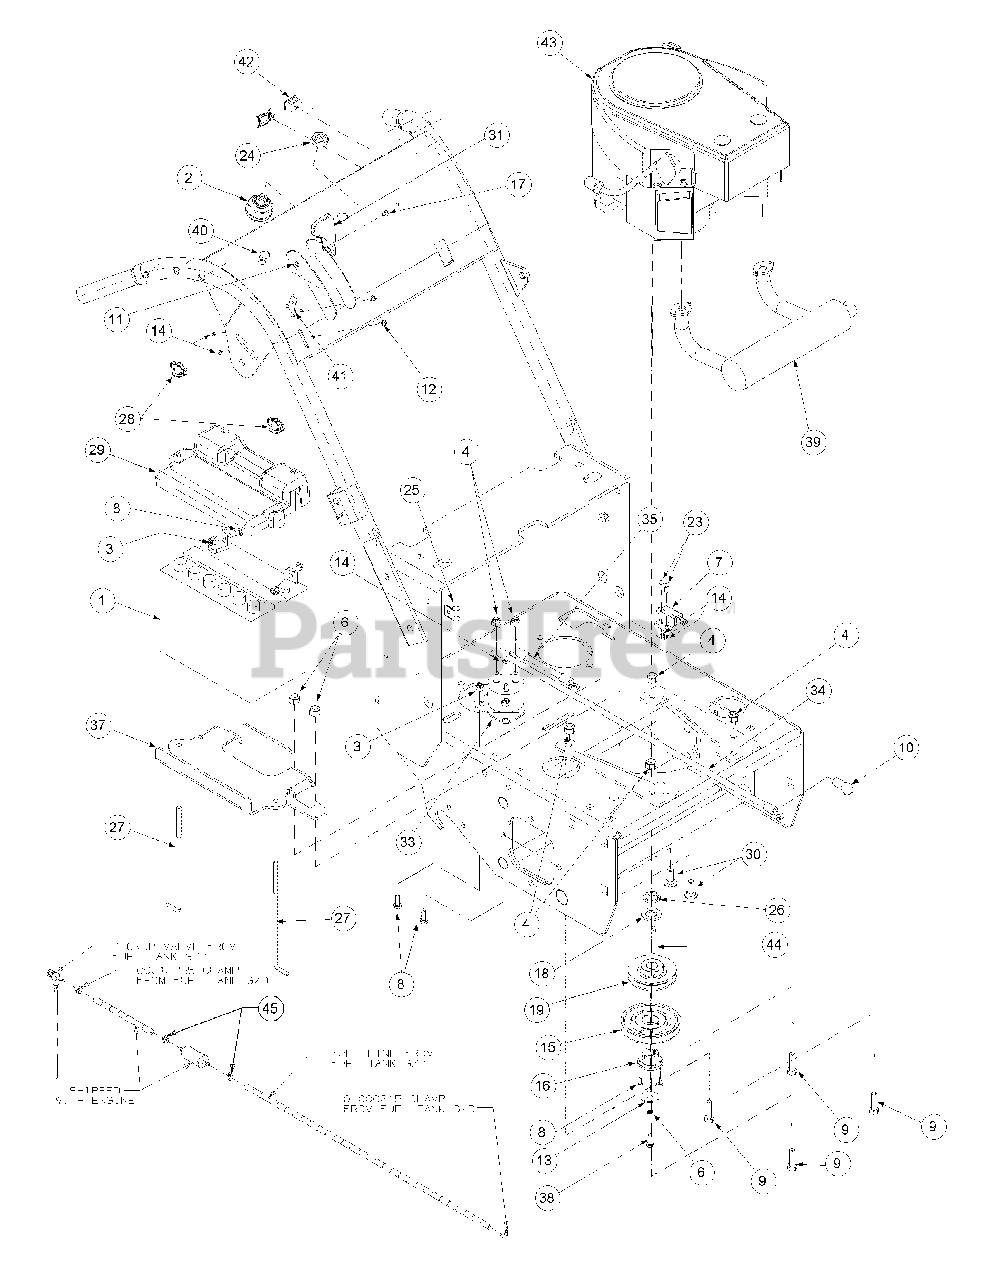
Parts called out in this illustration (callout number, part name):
1	Battery 12V
2	Ignition Switch
3	Lock Nut Nylon Insert, 1/4-20
4	Nylock Nut, 5/16-18
5	Nylock Nut, 3/8-16
6	Lock Washer, 7/16
7	Delta Switch
8	Hex Cap Screw, 1/4-20, .75
9	Hex Cap Screw, 5/16-18 x 2
10	Rubber Boot, 1" OD
11	Nut, 8-32, w/ star washer
12	Screw, Hex Washer w/slot, 10-32x1/2
13	Clutch Washer
14	Lock Nut, Nylon Insert, #10-32
15	Deck Pulley
17	Machine Screw, 8-32
18	Washer
19	Cast Pulley, 1" Bore
20	Hydro Pump Belt
21	Black Battery Cable, 17" Long
23	Machine Screw, 10 -32 x 5/8
24	Nut w/cap 5/8-32
25	Support Clamp 3/8 OD
26	Engine Pulley Spacer, 12.5
27	Battery Holdown Rod
28	Wing Nut, 1/4-20 w/Bell Washer
29	Battery Cover
30	Carriage Bolt, 3/8-16 x 1
31	Throttle Control Knob
32	Harness Hourmeter
33	Magnetic Solenoid Switch
34	24" Red Battery Cable
35	5" Red Battery Cable
36	Harness Adapter Kawasaki
37	Battery Bracket
38	Capscrew, 7/16-20 x 1-1/4
40	Cable Choke
41	Control Throttle w/Detent
42	Hour Meter
43	17 HP Kawasaki Kai Engine
44	Bevel Key, 1/4 x 1/4 x 2.75
45	Hose Clamp, 1/4-5/8, SS
